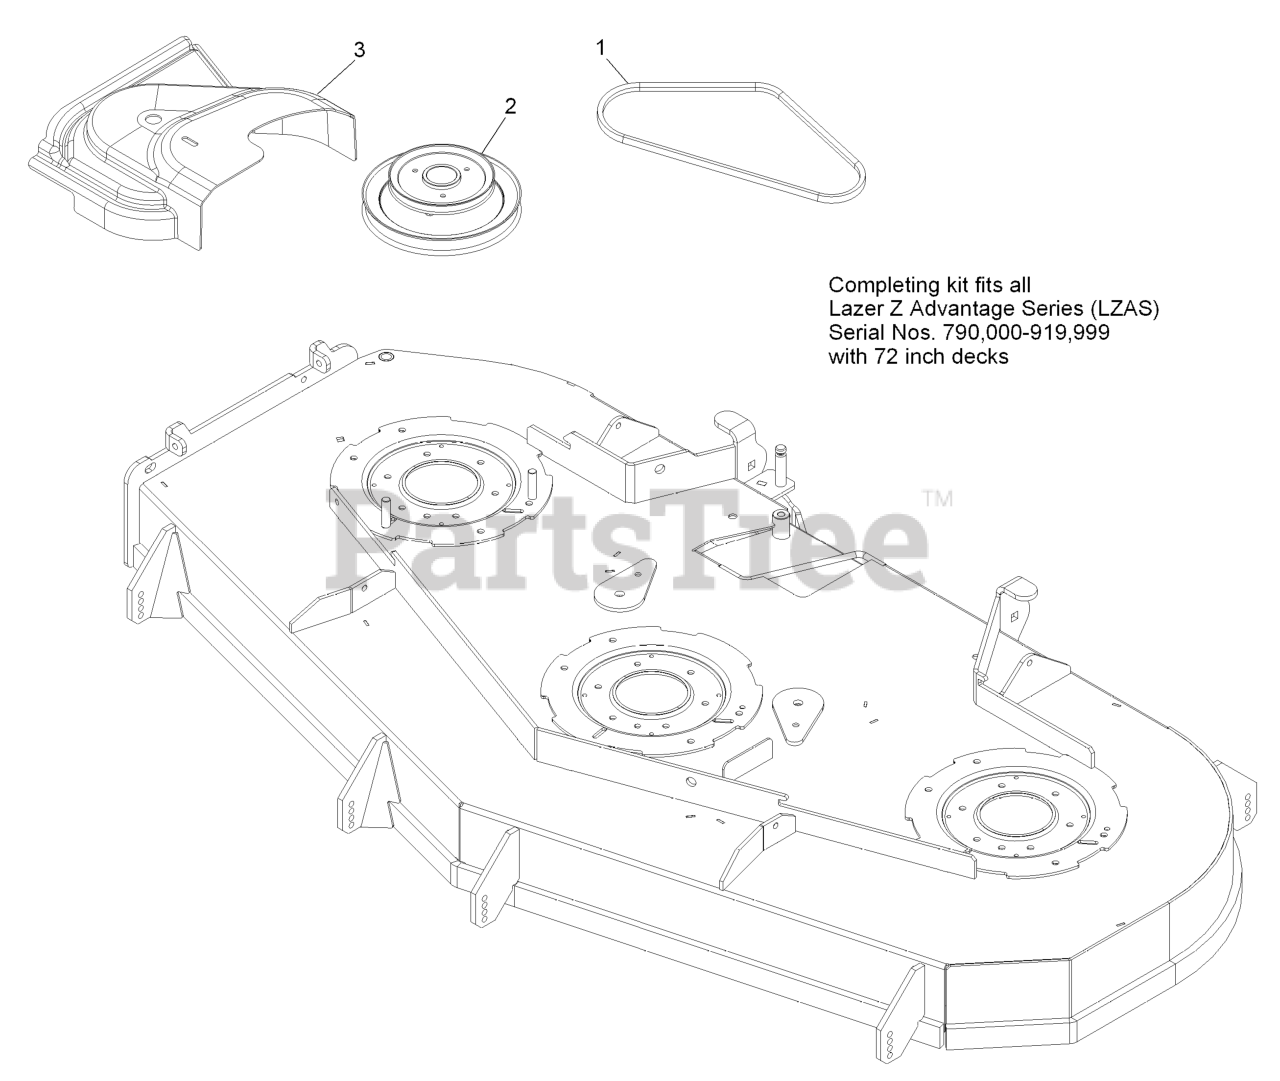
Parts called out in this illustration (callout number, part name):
1	BELT, BLOWER DRIVE 72
2	JACKSHAFT,UV DRIVE 724
3	COVER,BELT UV 72
